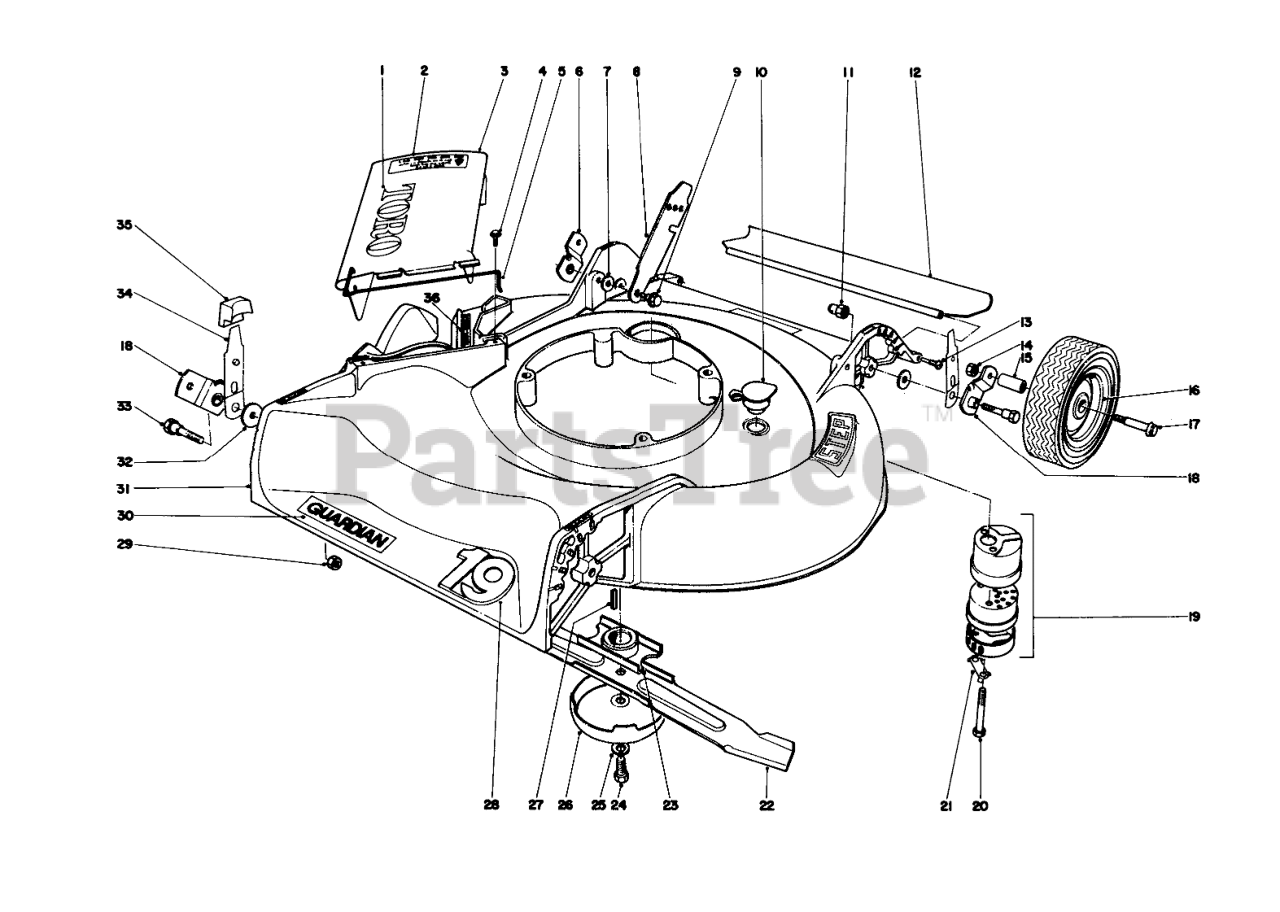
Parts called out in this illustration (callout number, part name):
1	Decal
2	Decal Caution
3	Deflector Cover Assembly (Incl. Ref. #1, 2 & 5)
4	SCREW
5	SPRING HINGE
6	Pivot Arm
7	SPACER
8	Latch
9	SCREW-SHOULDER
10	WASHOUT PLUG
11	HANDLE PIVOT NUT
12	SHIELD - TRAILING
13	SAFTEY SHIELD SCREW
14	Nut
15	Bushing
16	Wheel & Tire (Incl. Ref. #15) (Model 19400)
18	Pivot Arm
19	Muffler Assy. (Incl. Ref. #20 & 21)
20	SCREW-HH
21	CLIP - LOCKING
22	Blade
23	Blade Retailer
24	SPECIAL SCREW
25	WASHER-LOCK
26	Anti Scalp Cup
27	KEY-SQUARE
28	Emblem Deck
29	Nut
30	Decal Deck
31	Housing
32	Washer
33	Pivot Screw
34	SPRING ARM ASM
35	Knob Arm
36	Decal
